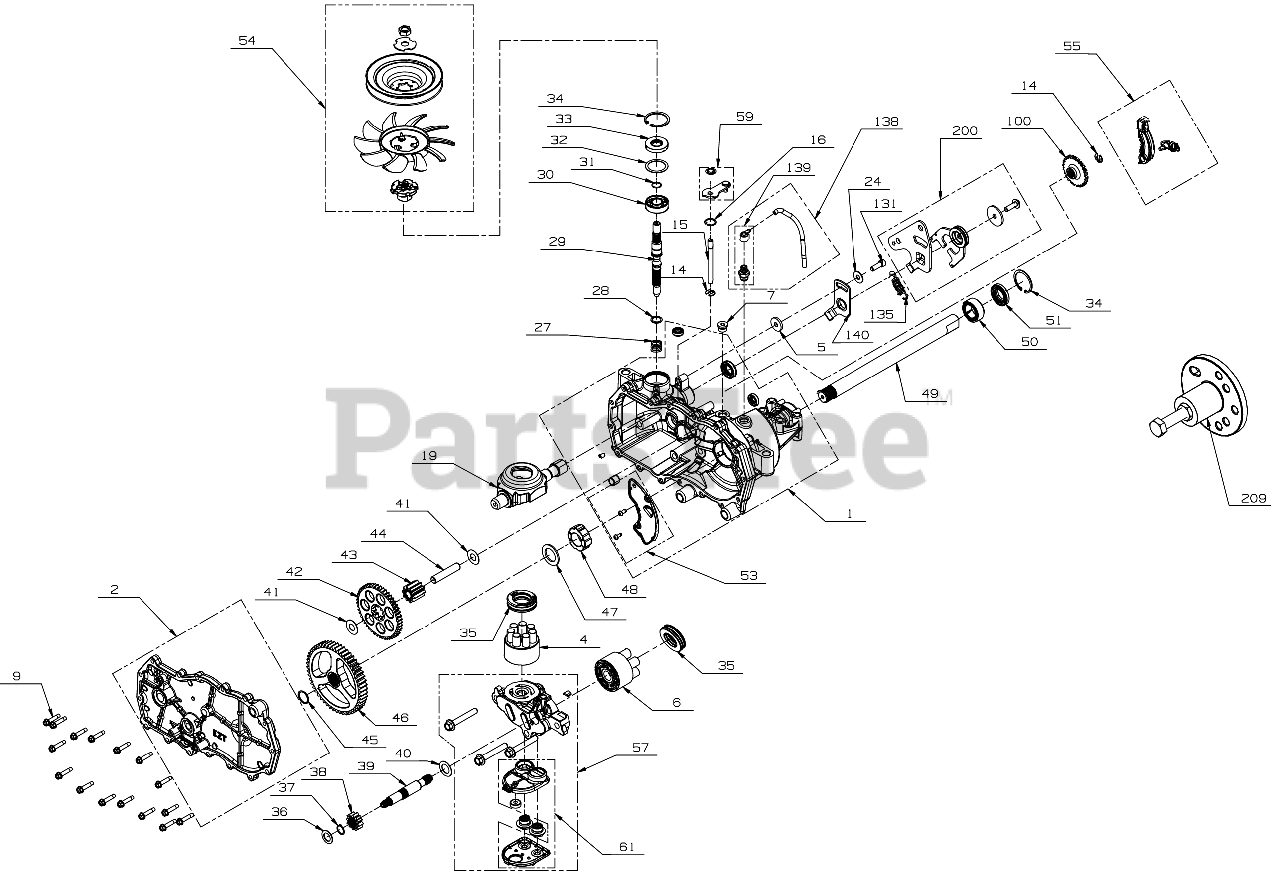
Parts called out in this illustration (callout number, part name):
1	HOUSING KIT-MAIN
2	HOUSING KIT-SIDE
4	BLOCK KIT-7 PISTON
5	SPACER .32 x 1.005 x .179
6	BLOCK KIT-5 PISTON
7	PLUG-STRAIGHT THRE
9	SCREW-WASHER HEAD
14	RETAINING RING
15	BYPASS RODS
16	RETAINING RING
19	SWASHPLATE-TRUNNION
24	FLAT WASHER
27	SPRING-BLOCK
28	THRUST WASHER
29	INPUT SHAFT
30	BALL BEARING
31	RETAINING RING
32	WASHER 1.23X1.56X
34	RETAINING RING
35	THRUST BEARING
36	FLAT WASHER
37	RETAINING RING
38	PINION GEAR 12T
39	MOTOR SHAFT
40	MOTOR SHAFT WASHER
42	GEAR 10T/49T
43	GEAR-10T JACKSHAFT
44	PIN-JACKSHAFT
45	RETAINING RING
46	GEAR-BULL 52T
47	WASHER 1.018 x 1.
48	SLEEVE BEARING
49	AXLE SHAFT
50	SLEEVE BEARING
53	PLATE KIT (RH) EXPANSI
54	KIT-FAN & PULLEY
54	FAN-7.0 (10 BLADE)
54	HUB-PULLEY
54	WASHER-SLOTTED
55	BRAKE ARM KIT
57	SECTION KIT-CENTER
58	SEALANT-HOUSING
59	ARM KIT-BYPASS
61	FILTER ASSEMBLY
100	DISC-BRAKE COG
131	SCREWS KIT-RTN
135	EXTENSION SPRING
138	HOSE KIT-BREATHER
139	CAP KIT-BREATHER
140	ARM-NEUTRAL (RH)
200	RETURN KIT-NEUTRAL (RH) ZT2800 RZT
209	PULLER KIT-HUB
